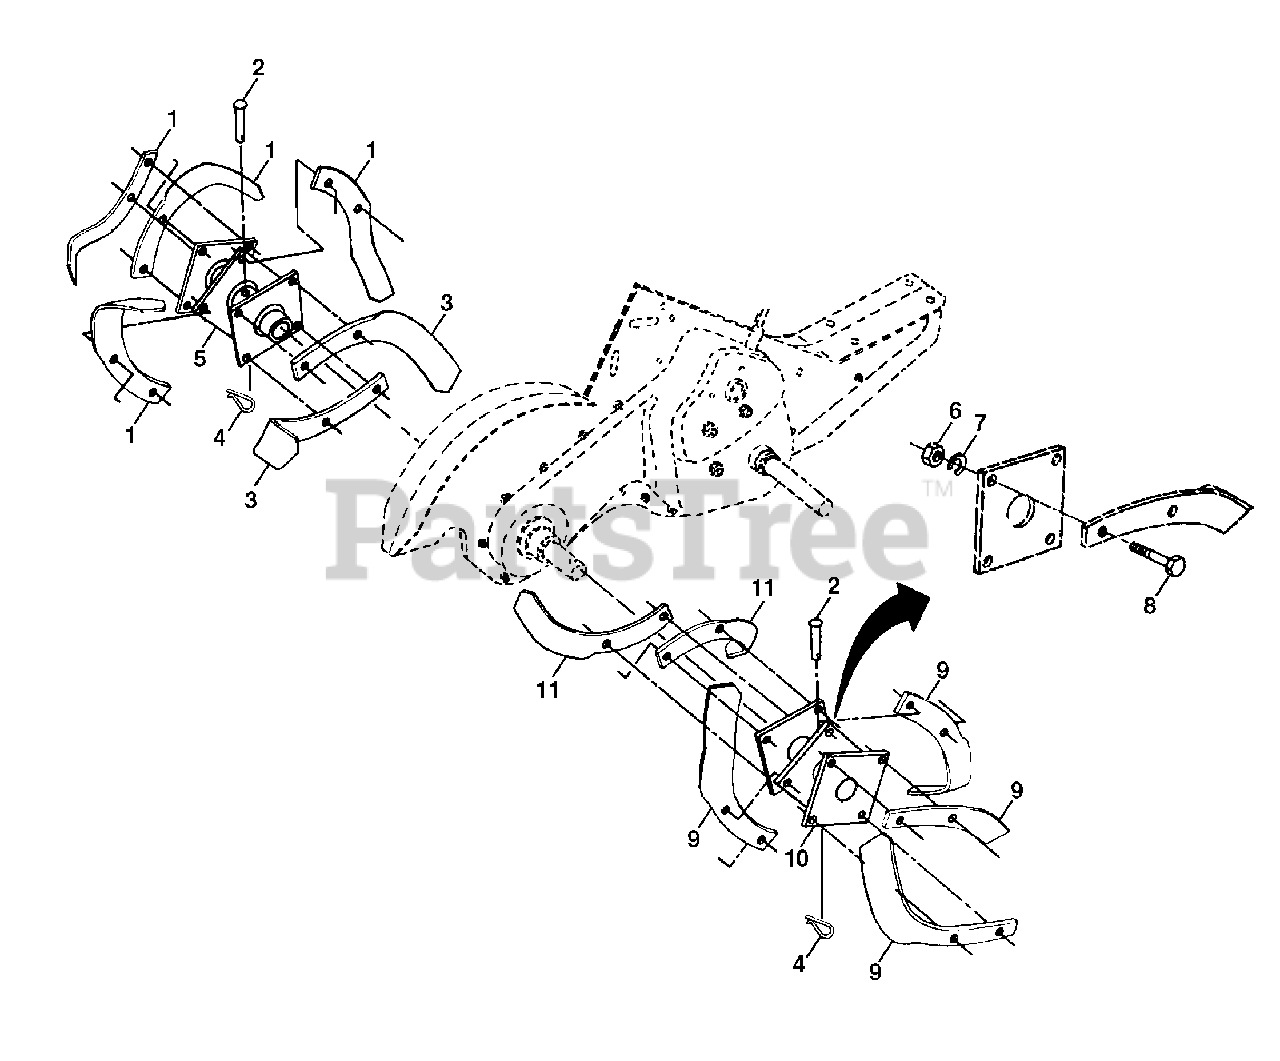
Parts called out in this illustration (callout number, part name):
1	Tine, Outer, L.H.
2	Clevis Pin
3	Tine, Inner, L.H.
4	Retainer, Spring
5	Assembly, Hub and Plate, L.H.
6	Nut, Hex 3/8-24
7	Washer, Lock 3/8
8	Bolt, Hex 3/8-24 x 1
9	Tine, Outer, R.H.
10	Assembly, Hub and Plate, R.H.
11	Tine, Inner, R.H.
